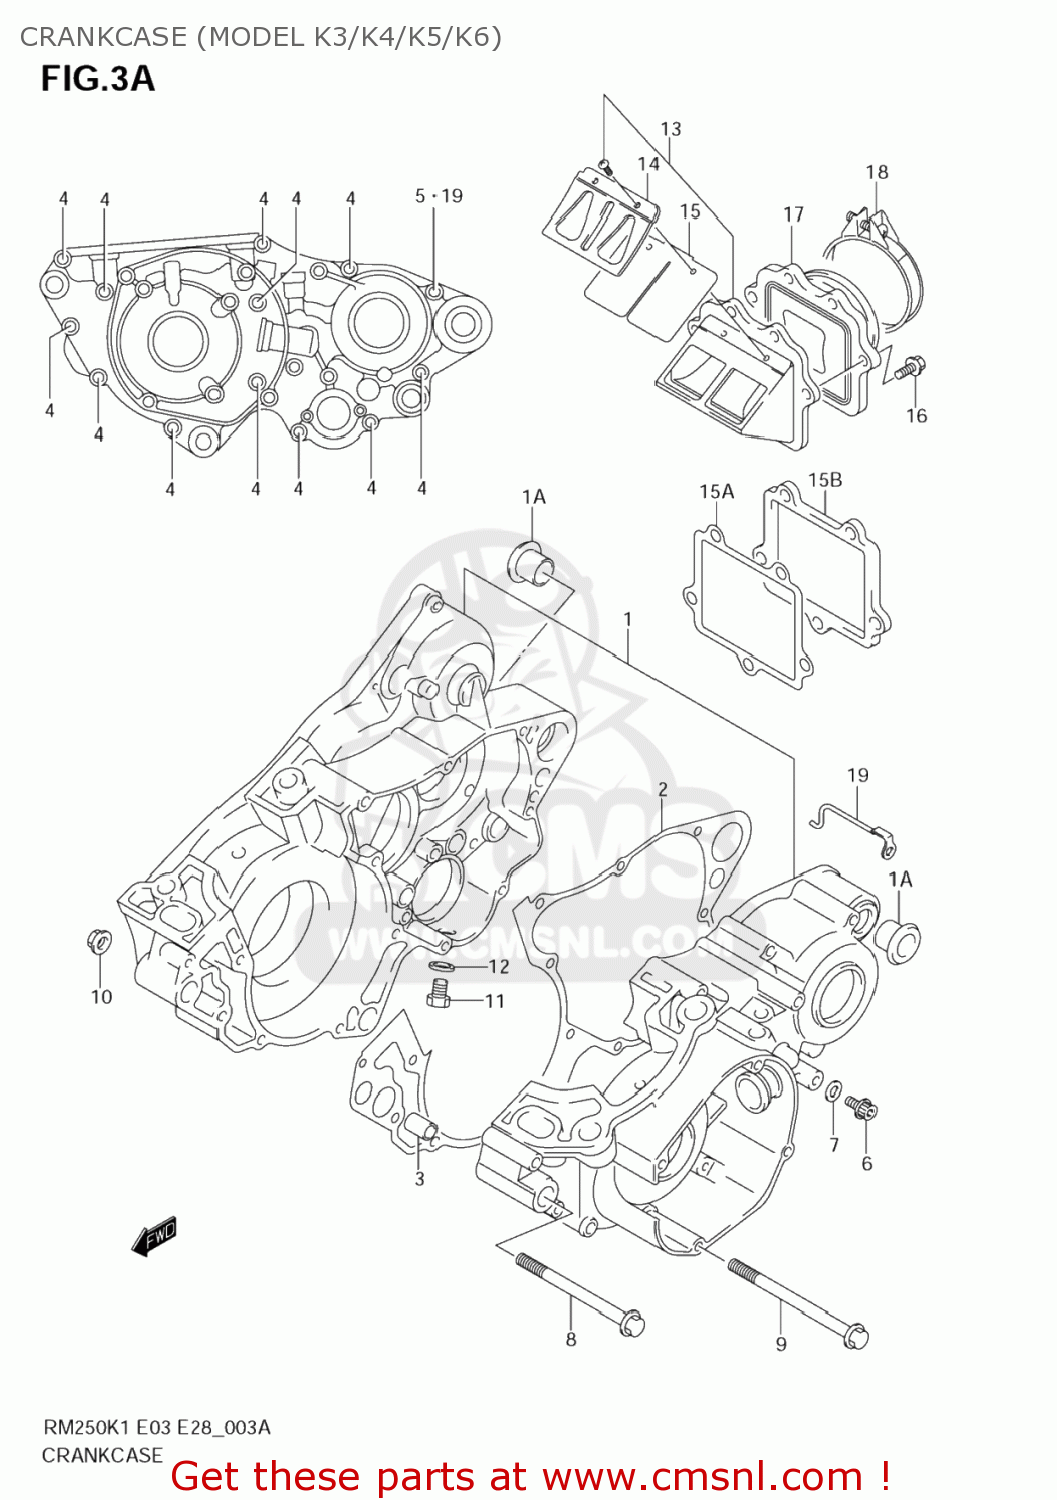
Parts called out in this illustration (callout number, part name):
1	CRANKCASE SET
1A	BUSH,ENGINE PIVOT
2	GASKET,CRANKCASE (NAS)
3	PIN(13X10.4X20)
4	BOLT(6X50)
5	BOLT(6X65)
6	BOLT
7	GASKET(6.2X11X1).2 (NAS)
8	BOLT(10X105)
9	BOLT(10X118)
10	NUT
11	PLUG
12	GASKET(12.1X16.2X3.7) (NAS)
13	VALVE ASSY,REE
14	STOPPER,REED VALVE
15	VALVE,REED
15A	GASKET,REED VALVE (NAS)
15B	SPACER,REED VALVE
16	BOLT,6X20
17	PIPE,INTAKE
18	CLAMP
19	GUIDE,CARBURETOR HOSE
